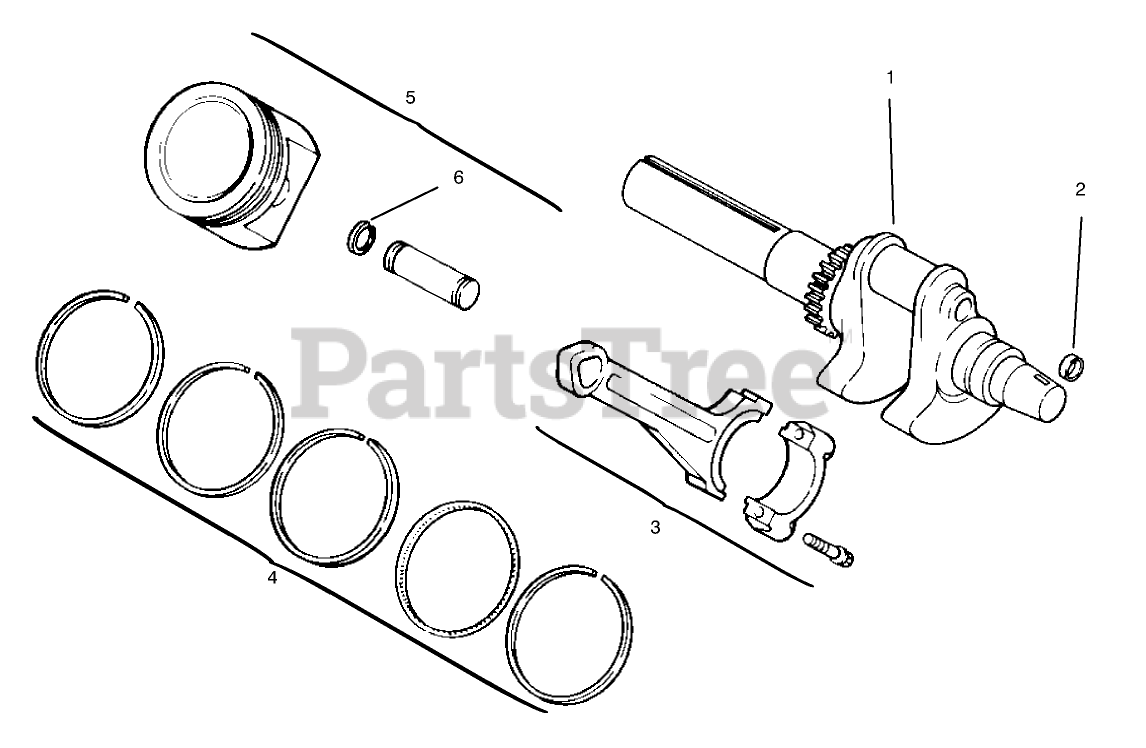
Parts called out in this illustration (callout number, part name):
1	Crankshaft
3	Connecting Rod (Std.)
4	Set-Ring (STD)
5	Piston w/Ring Set (Std.)(Incl. Ref. #4-6)
6	RETAINER-PIN, PISTON
